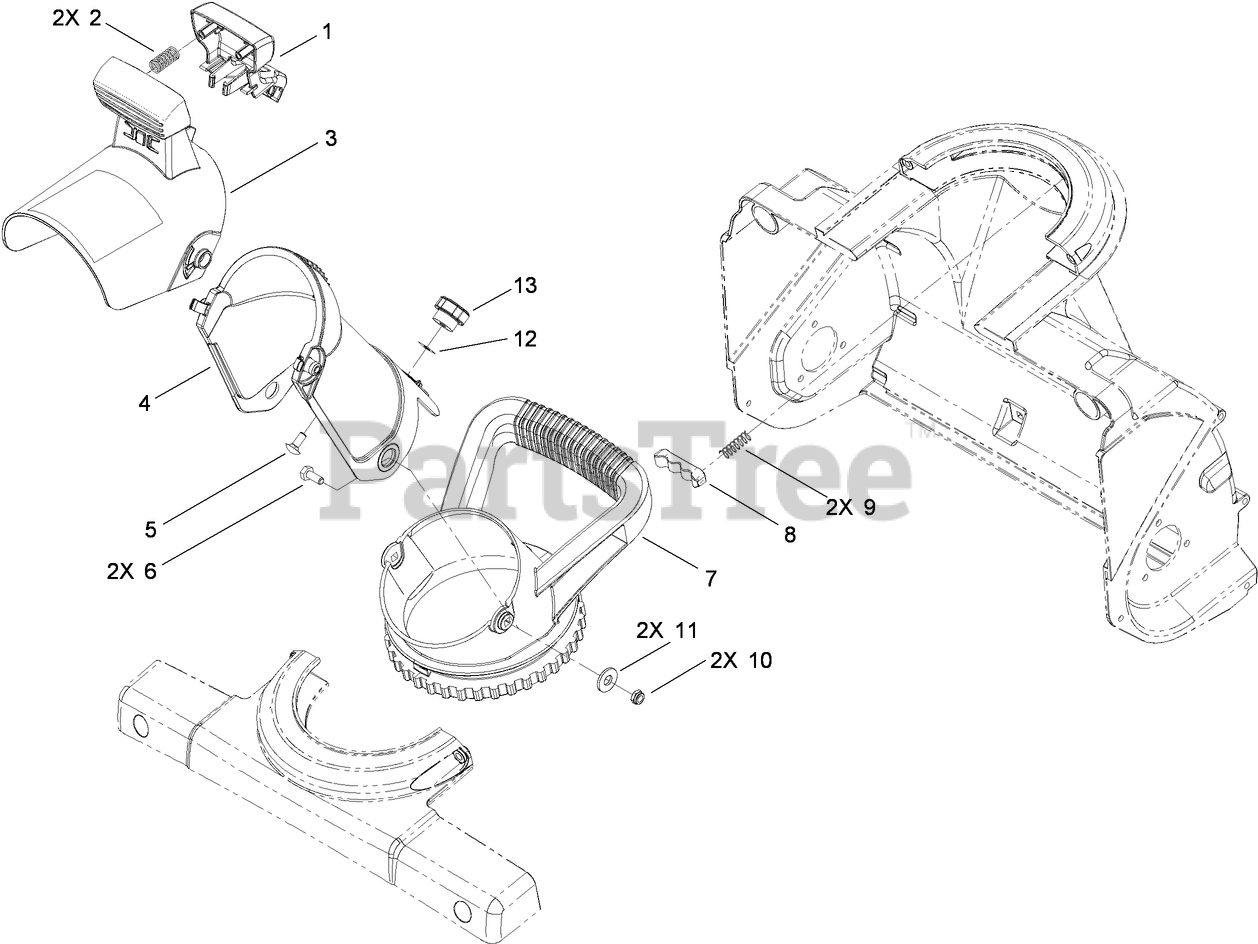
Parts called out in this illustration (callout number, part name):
1	TRIGGER-DEFLECTOR
3	CHUTE DEFLECTOR ASM
4	CHUTE-DISCHARGE
5	SCREW-CARR
6	SCREW-HH
7	HANDLE-CHUTE
8	DETENT-CHUTE
9	SPRING-COMPRESSION
10	NUT-LOCK, NI
11	WASHER-FLAT
12	PUSHNUT-RETAINER, BOLT
13	KNOB-CHUTE
